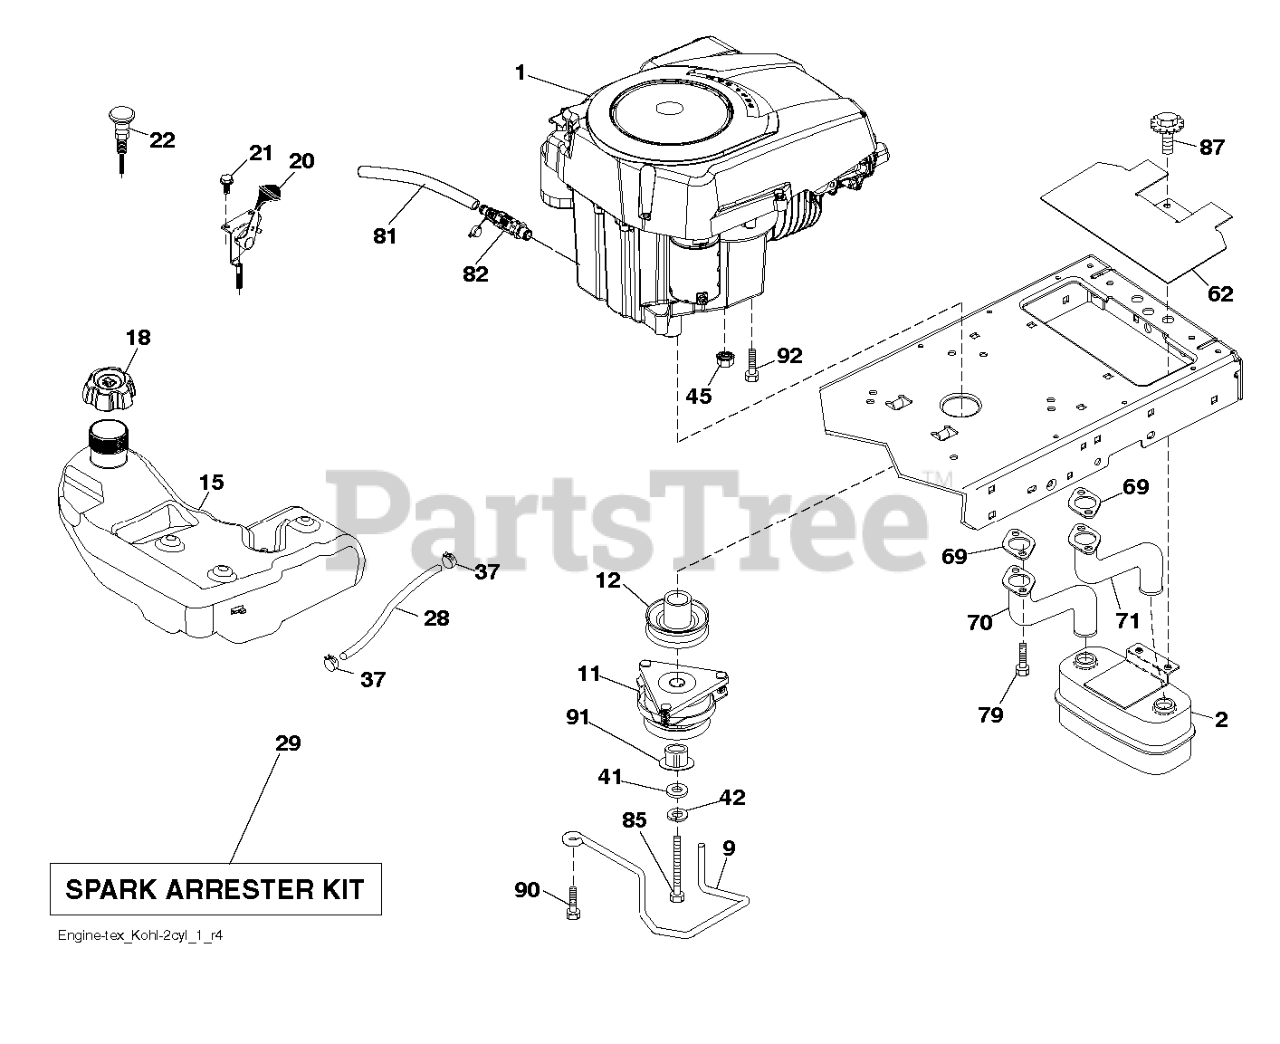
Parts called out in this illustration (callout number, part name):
2	MUFFLER.TWIN.CYL.LOW.TONE
9	KEEPER.BELT.ENGINE.4.2
11	CLUTCH.ELECTRIC.LT.48"*
12	PULLEY.ENGINE.TUFFTORQ
15	RP_TANK.ASSY.3.GAL.EPA
18	CAP.ASM.FL.RITCH.3"E10.SYM.498
20	THROTTLE CONTROL
21	SCREW.#10 X 0.750.BOS
22	CONTROL.CHOKE.ERGO.PUSH-IN.BLA
28	LINE.FUEL.64"REAR.EMIS
29	KIT.SPARK ARRESTOR 794945 B&S
37	HOSE CLAMP
42	LOCKWASHER
45	NUT
62	SHIELD.HEAT.MUFFLER
69	GASKET.EXHAUST.KOHL.CV18-CV26
70	RP.PIPE-EXHAUST LH
71	RP.PIPE-EXHAUST RH
79	SCREW.SOCKET HD.5/16-1
81	TUBE, DRAIN OIL ASM.
82	VALUE.OIL.DRAIN
85	BOLT HEX 7/16-20X4-1/4"
87	BOLT.5/16-18UNCX3/4 W/SEMS.BLK
90	SCREW 3/8-16X1
91	BUSHING.1.375OD
92	SCREW 3/8-16X1
